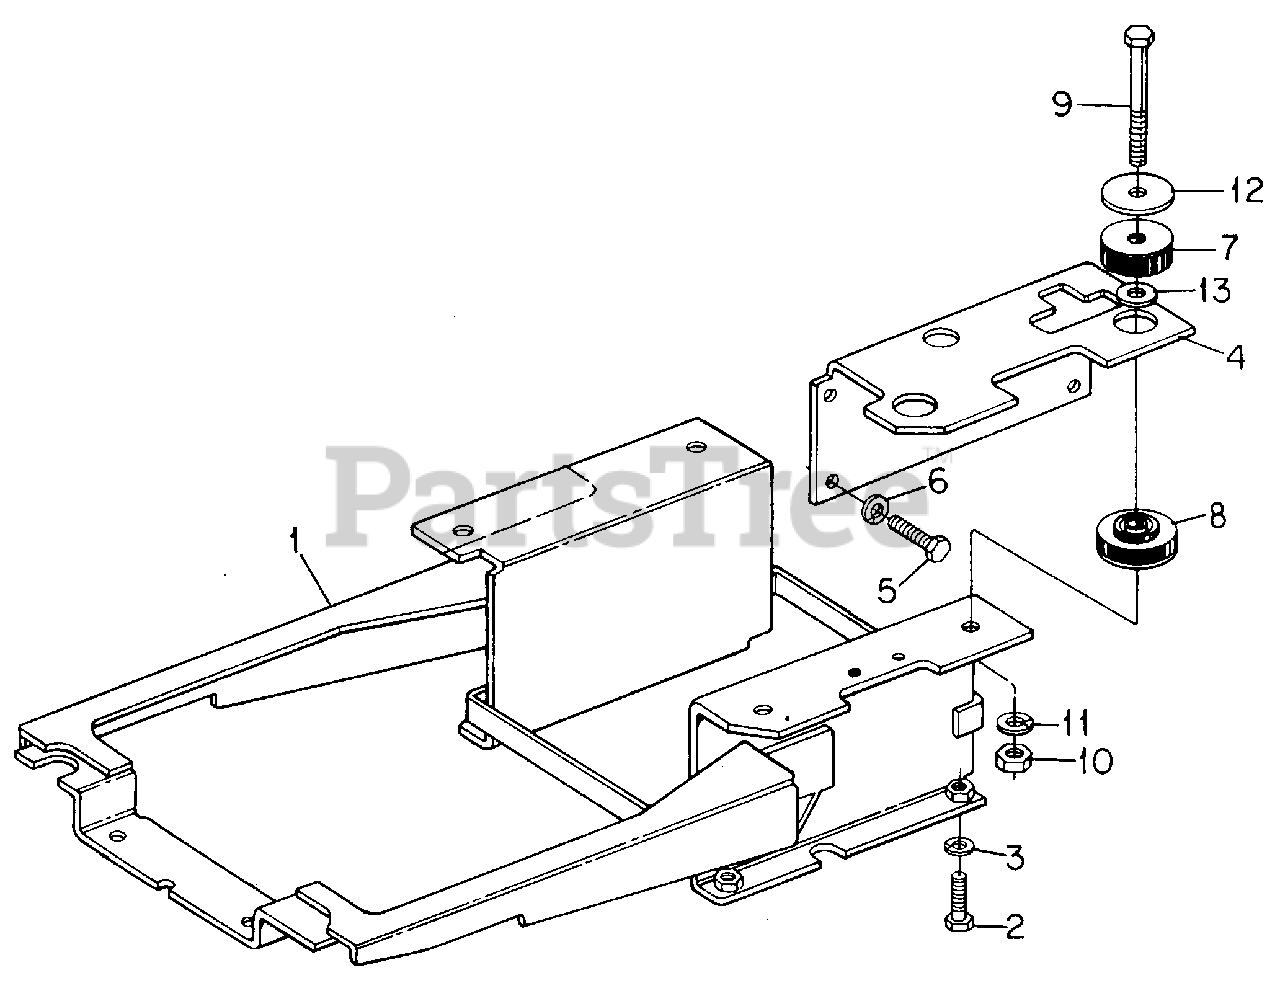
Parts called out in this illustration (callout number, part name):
1	Mount, Engine & Radiator
2	Bolt, 3/8 X 1-1/4 Type 5
3	Washer, 3/8 Lock
6	Washer, 10MM Lock
7	Mount, Engine
8	Mount, Engine Load
9	Bolt, 3/8 X 2-1/4 Type 5
10	Nut, 3/8 Type 5
11	Washer, 3/8 Lock
12	Washer, .406 X 1.500 X .105
13	Washer, Flat
